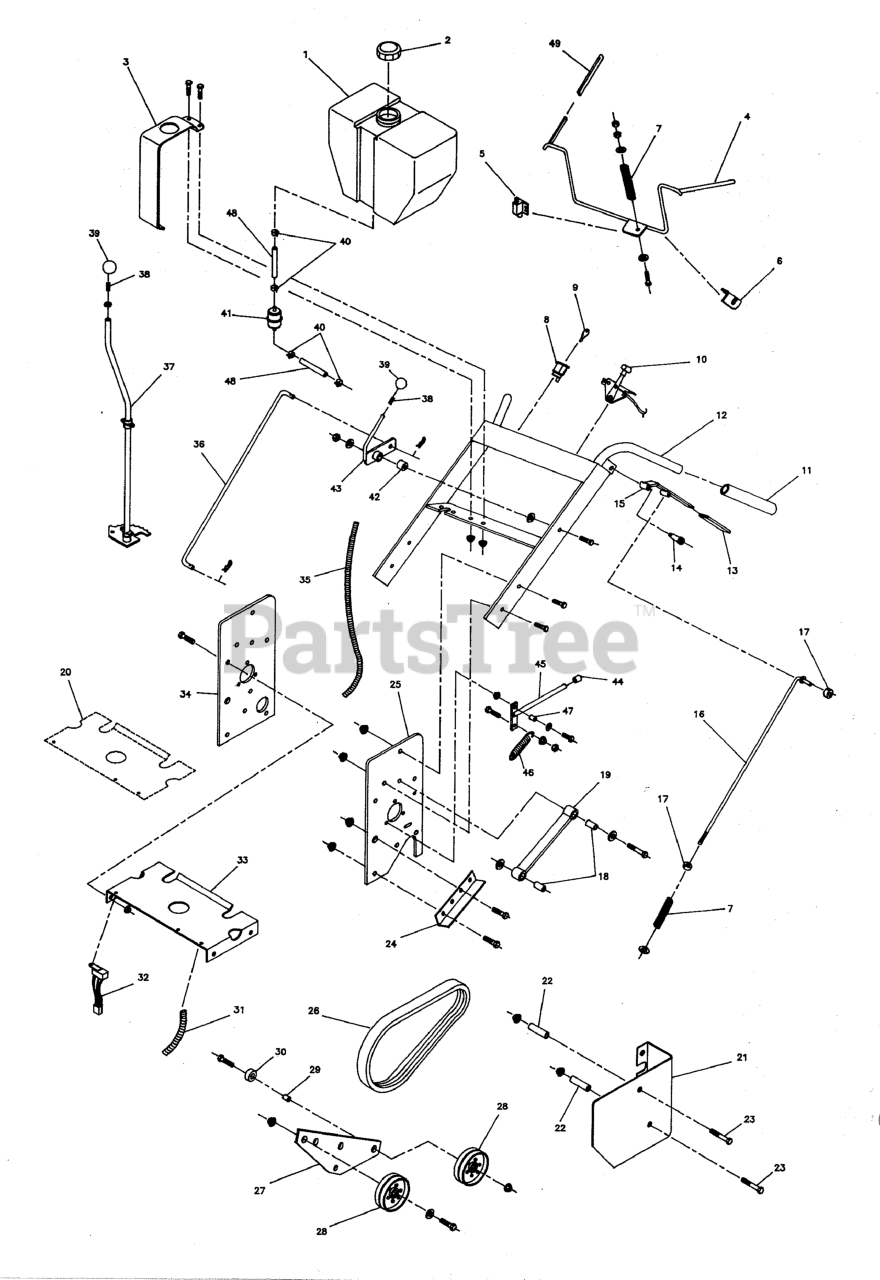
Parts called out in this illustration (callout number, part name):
1	FUEL TANK, 4 Gallon
2	CAP, Fuel Tank
3	FUEL TANK STRAP
4	Operator Presents Handle
5	SWITCH, Plunger, NO
6	Operator Present Bracket Left
6	Operator Present Bracket Right
7	SPRING, Compression
8	SWITCH, Ignition
9	Ignition Key
10	CABLE, Throttle, 38"
11	GRIP, Foam
12	Handle Bar Weldment
13	GRIP, FOAM, 1/4 X 1 X 4.1
14	SHOULDER BOLT, 1/2 x 1-1/2
15	BRAKE HANDLE
16	Brake Rods
17	COLLAR, 5/16" Set
18	BUSHING, Brass
19	Clutch Arm
20	Safety Walk
21	Guard
21	Guard Right Side
22	Belt Guide
23	BOLT, 5/16-18 x 2-1/2
24	Ramp Angle
25	Left Side Plate
26	BELT, Double-A Section
27	Clutch Lever
28	PULLEY, Idler
29	SPACER, .38 x .50 x .27
30	Bearing
31	WIRE LOOM, 6"
32	Saftey Interlock
32	Interlock
33	Gas Tank Mount
34	Right Side Plate
35	WIRE LOOM, 34"
36	Connecting Rod
37	Speed Control Lever
38	STUD, 5/16-18 x 1-1/4"
39	Black Knob
40	CLAMP, Hose
41	FUEL FILTER
42	Nylon Bushing
43	Blade Engagement Lever
44	Plastic Boot
45	Spring Tensioner
45	Spring Tensioner Right Side
46	SPRING, Extension
47	SPACER, .26 X .38 X .50
48	4" Long Fuel Line
49	GRIP, Vinyl
